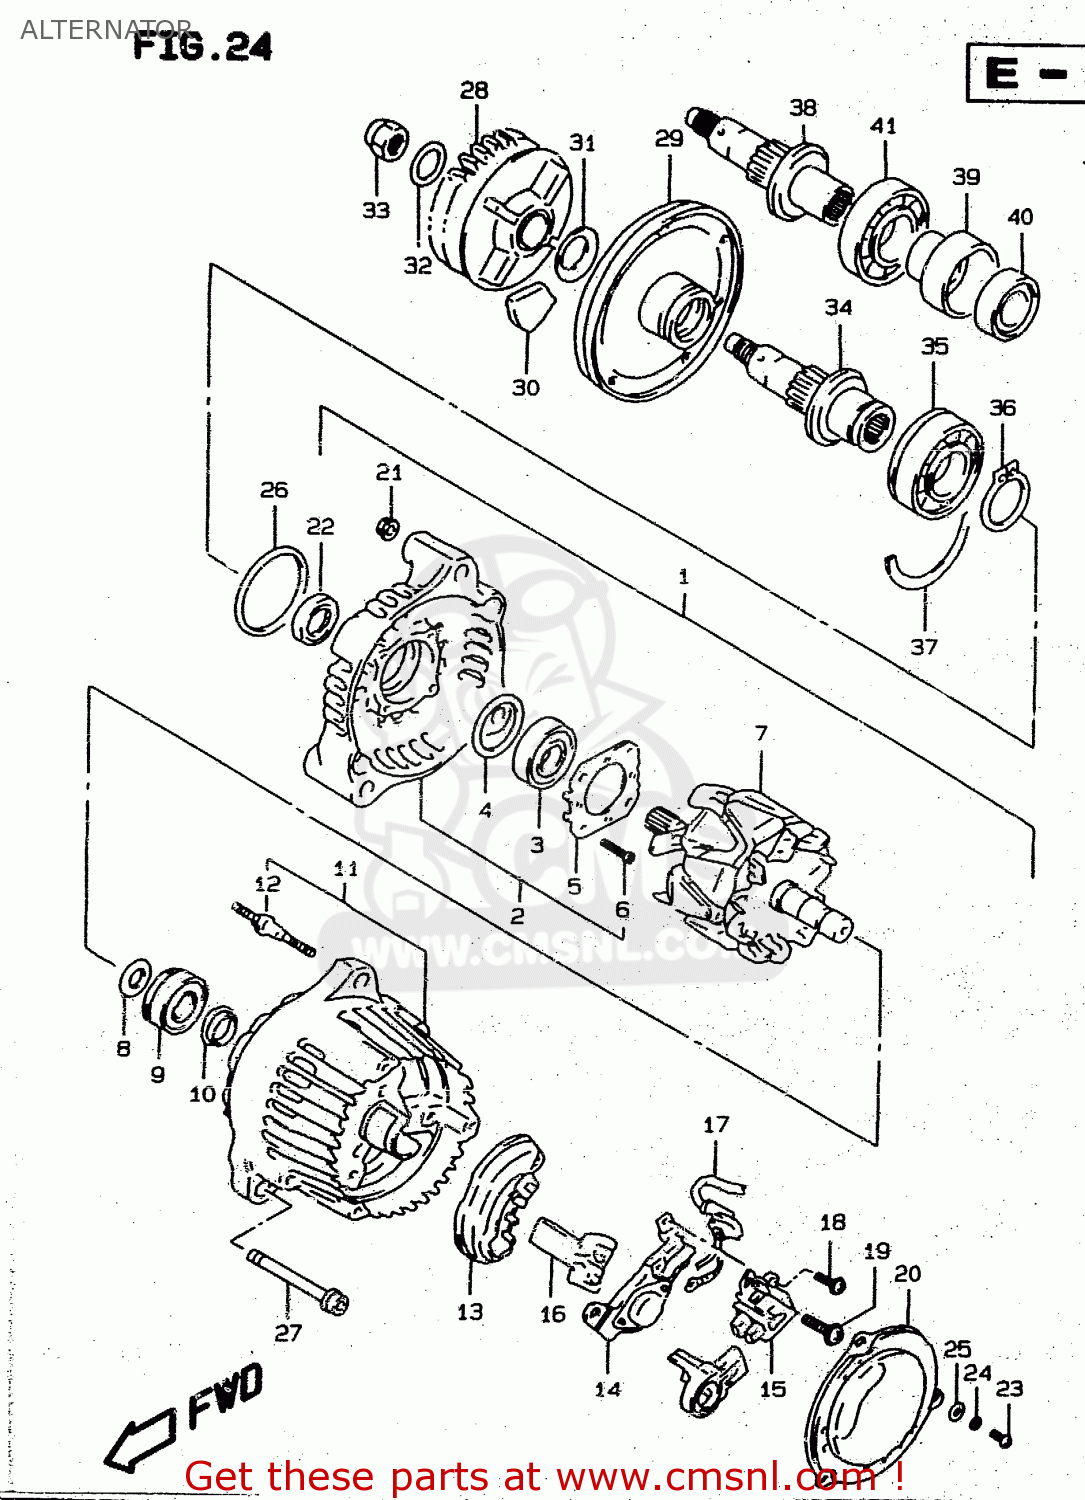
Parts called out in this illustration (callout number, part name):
1	ALTERNATOR ASSY
2	FRAME,DRIVE END
3	BEARING
4	COVER,BEARING
5	RETAINER,BEARING
6	SCREW,BEARING RETAINER
7	ROTOR ASSEMBLY
8	COVER,BEARING
9	BEARING
10	COVER(2)
11	FRAME,END
12	STUD BOLT
13	HOLDER,RECTIFIER
14	REGULATOR
15	HOLDER,BRUSH
16	COVER,RECTIFIER
17	WIRE,LEAD
18	SCREW 4X6
19	SCREW
20	COVER
21	NUT
22	SERVICE KIT(A)
23	SCREW
24	LOCK,WASHER
25	WASHER
26	O RING
27	BOLT
28	GEAR,GENERATOR DRIVEN
29	HOUSING,GENERATOR DAMPER
30	DAMPER,GENERATOR
31	WASHER
32	WASHER
33	NUT
34	SHAFT,GENERATOR DRIVE
35	BEARING(25X52X15)
36	CIRCLIP
37	C RING
38	SHAFT,GENERATOR DRIVE
39	HUB,GENERATOR DRIVE
40	COUPLING COMP,GENERATOR
41	BEARING(25X52X13)
